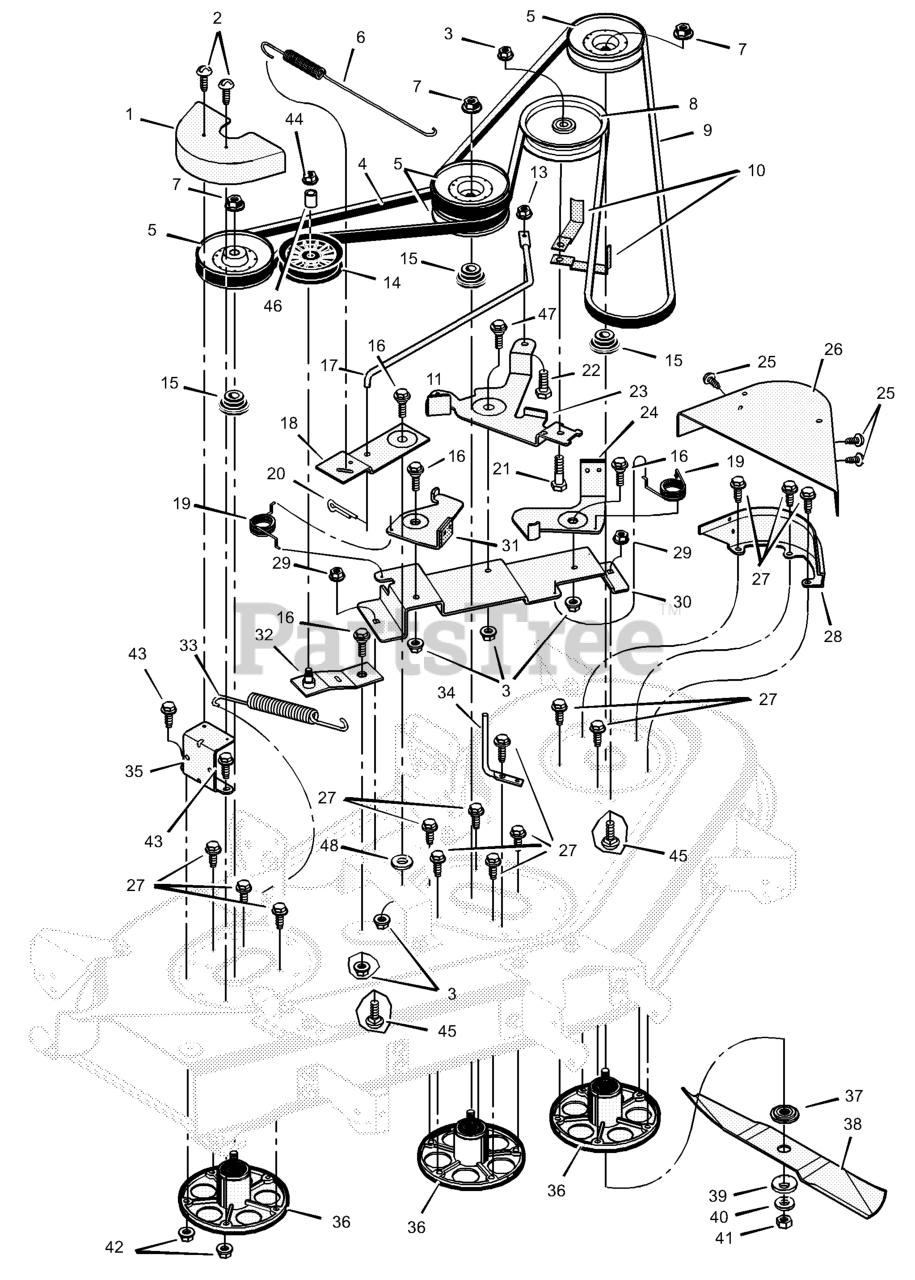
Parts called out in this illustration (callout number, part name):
1	Cover, Right Pulley
2	Screw
3	Nut
4	Belt, Secondary
6	Spring, Extension
8	Pulley, Idler
9	Belt, Primary
10	Spring, Belt Guide
14	Pulley, Backside Idler
16	Bolt, Shoulder
18	Bellcrank
19	Spring, Torsion
20	Pin, Cotter
21	Bolt
22	Bolt, Shoulder
23	Bracket, Idler
24	Assembly, Brake Arm & Pad
26	Cover, Left Pulley
27	Bolt
28	Bracket, Pulley Cover
29	Nut, Flange
30	Bracket, Brake
31	Assembly, Brake Arm & Pad
32	Assembly, Idler Arm
33	Spring, Extension
34	Guide, Belt
35	Bracket, Cover
36	Housing, Jackshaft
37	Adapter, Blade
38	Blade
39	Washer, Belleville
42	Nut
43	CAPSCREW, Hex Head, 5/16-18 x 1
44	Locknut
45	Bolt, Carriage
47	Bolt, Shoulder
48	Washer
